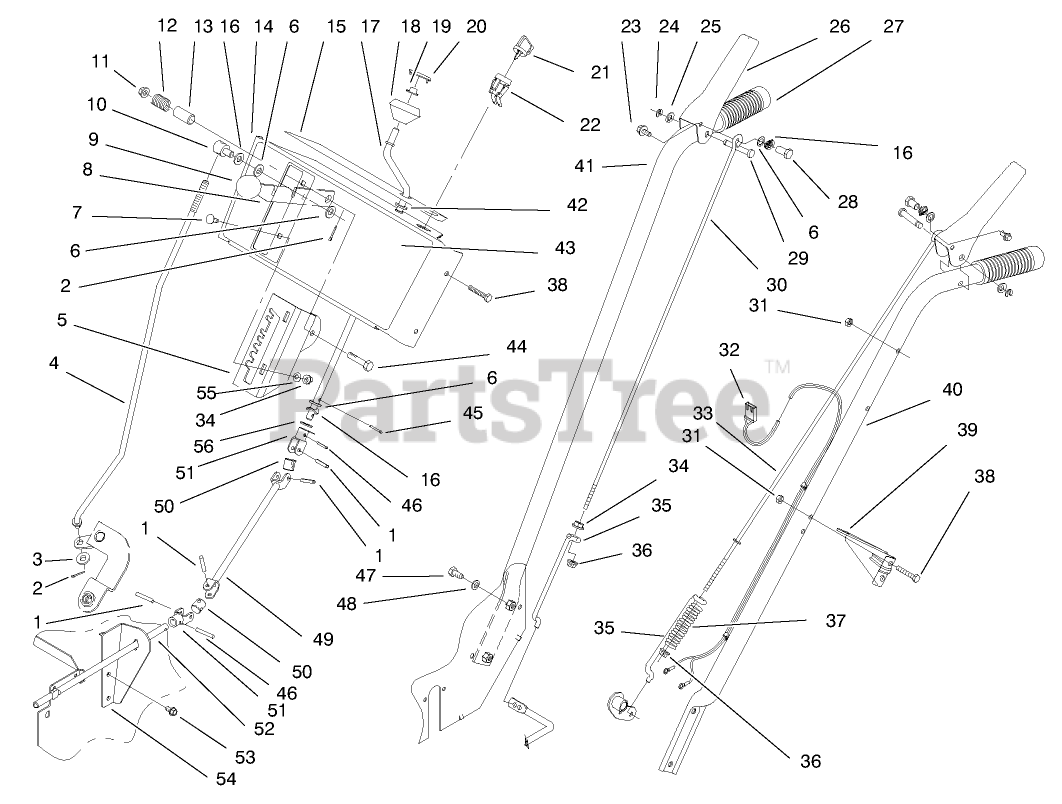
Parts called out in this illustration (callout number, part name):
1	PIN-ROLL, SLOTTED
2	PIN-COTTER
3	WASHER-FLAT
4	ROD - SHIFT
6	WASHER-FLAT
7	SCREW-CARR
11	NUT-HF
12	SPRING
13	SPACER
15	DECAL-BACK CONTROL PANEL
16	WASHER-SPRING
17	ROD - CHUTE CRANK
18	KNOB-CONTROL, CHUTE
19	NUT-PUSH
20	COVER-KNOB
21	KEY-IGNITION
22	SWITCH
23	SCREW-HHF
24	RING-CLIP
25	WASHER-PLAIN
26	HANDLE-CONTROL
28	POST-MOUNTING, LINKAGE
29	PIN-LEVER, CONTROL
30	ROD-UPPER ENGAGE AUGER
31	NUT-LOCK, NI
33	ROD - UPPER TRACTION
34	NUT-HF
35	ROD - LOWER TRACTION
36	NUT-HHF
37	SPRING
38	SCREW-HH
40	HANDLE - LEFT
43	DECAL - CONTROL PANEL
44	SCREW-HH
45	PIN-COTTER
46	PIN-SPRING
47	SCREW-HH
48	WASHER-BELLEVILLE
49	WA - CLEVIS ROD
50	BLOCK - PIVOT
51	WA - CLEVIS MOUNT
52	ROD - CHUTE CONTROL
53	SCREW-HWH
55	WASHER-FLAT
56	WASHER-RUBBER
